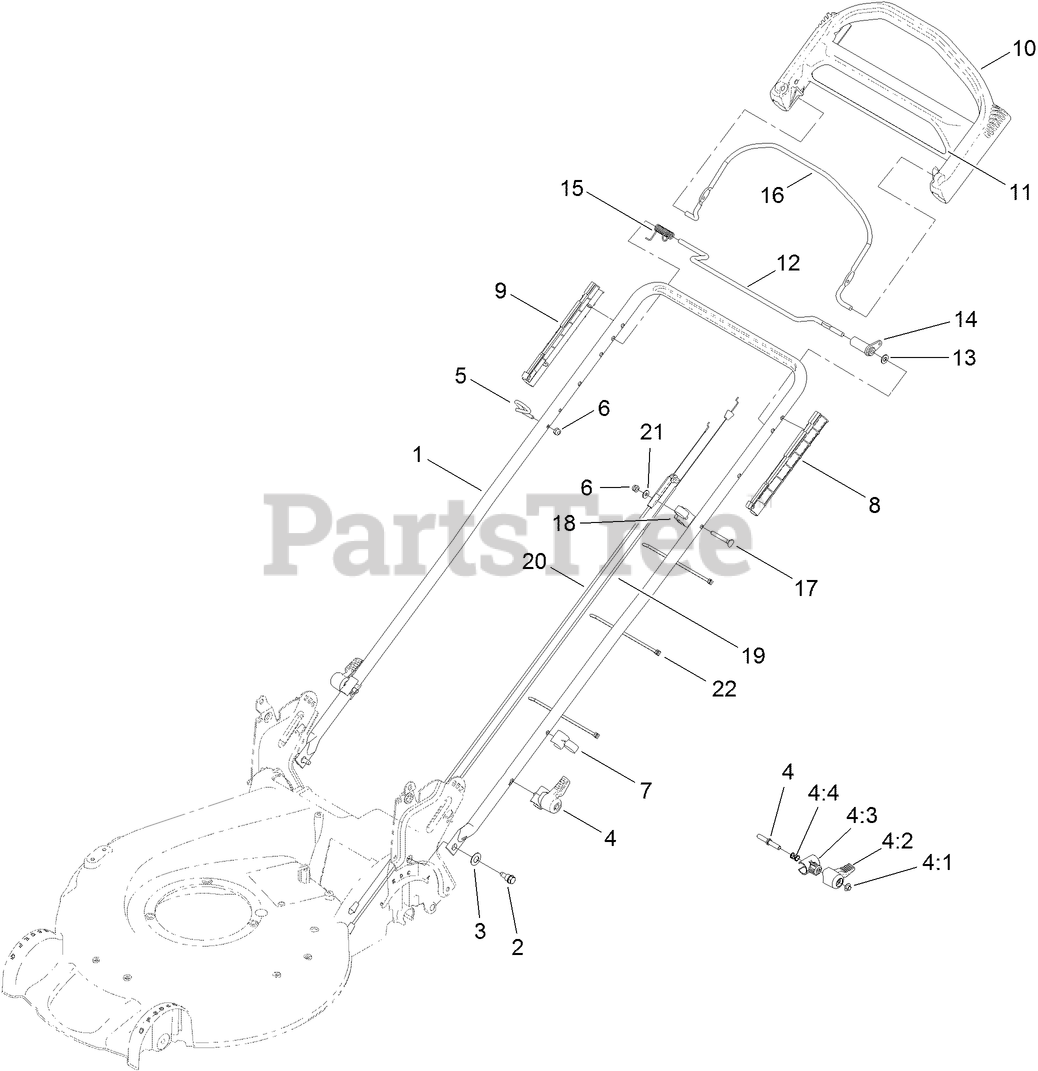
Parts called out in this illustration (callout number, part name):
2	BOLT-SHOULDER
3	WASHER-SPRING, CONICAL
4	QUICK RELEASE ASM
4:2	LEVER
4:3	ANCHOR-SPRING
4:4	SPRING-COMPRESSION
5	GUIDE-ROPE
6	NUT-LOCK, NI
7	GUIDE-CABLE
8	GUIDE-LH
9	GUIDE-RH
10	HANDLE-CONTROL
11	DECAL-HANDLE
13	WASHER-PLAIN
14	LEVER-TRACTION
17	SCREW
19	CABLE-TRACTION
20	CABLE-BRAKE
21	WASHER-FLAT
22	TIE-CABLE
